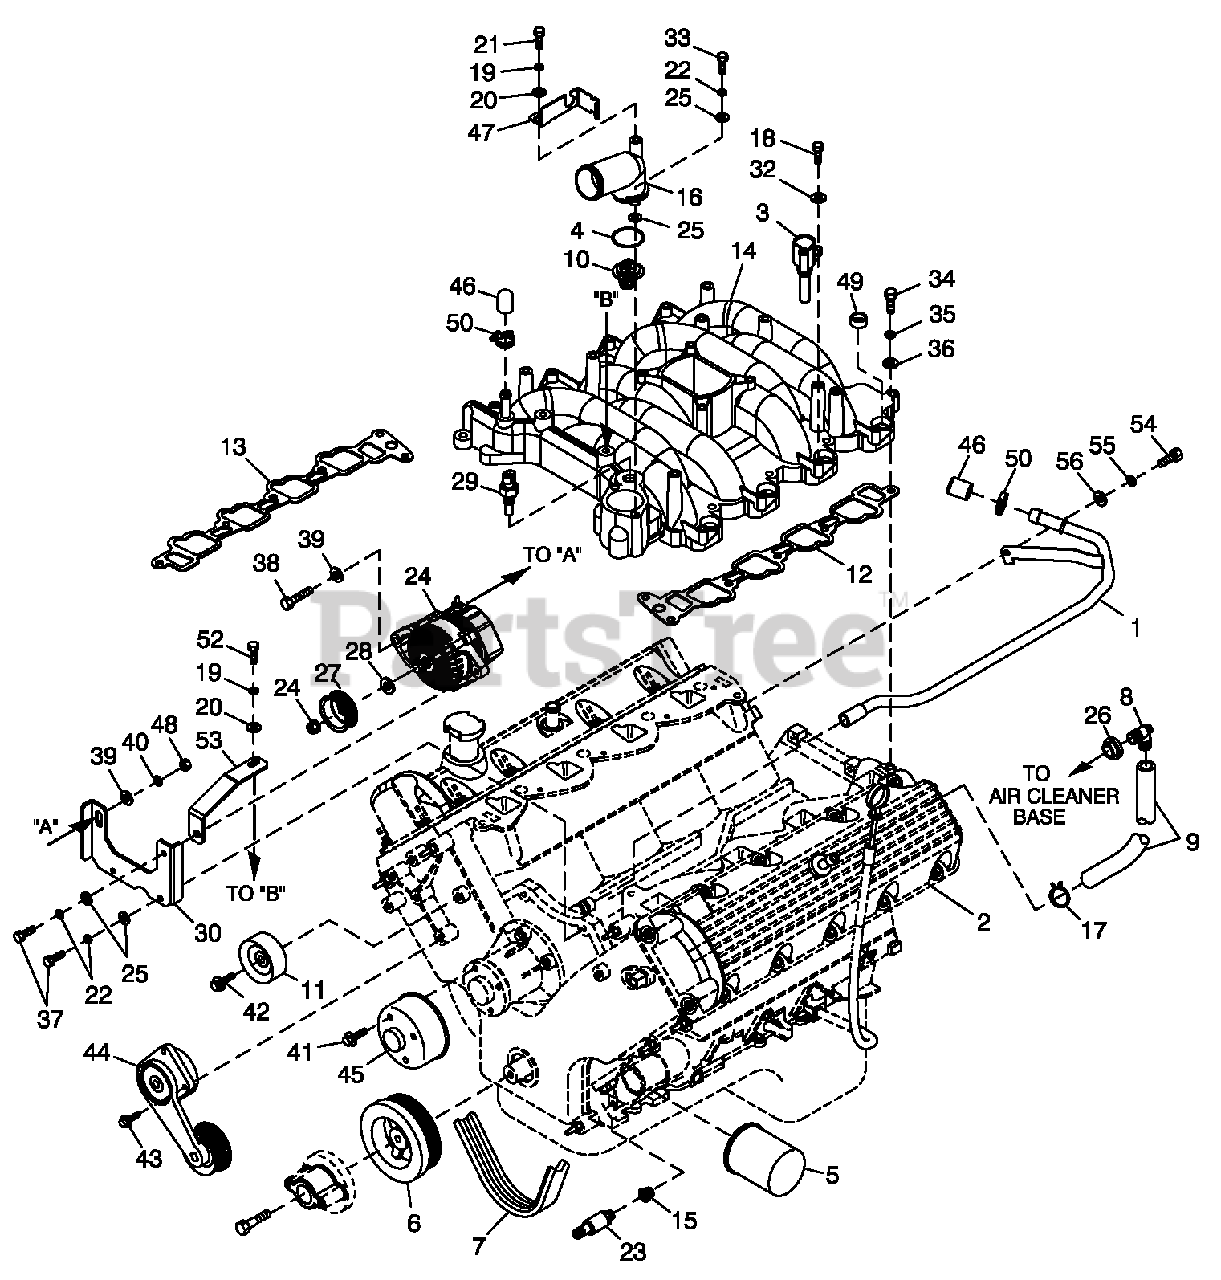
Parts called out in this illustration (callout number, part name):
1	TUBE COOLANT 4.6L
2	ENGINE 4.6L G3 (RWD)
3	IGNITION COIL ASSY
4	GASKET THERMOSTAT HOUSING G3
5	OIL FILTER
6	REWORK HARMONIC BALANCER
7	BELT SERPENTINE 54.72"
8	BARBED EL 90 3/4 PLASTIC
9	HOSE 3/4 ID SAE-30R2 (21"LG)
10	THERMOSTAT ASSY
11	PULLEY FAN BELT
12	GASKET INTAKE MANIFOLD LEFT
13	GASKET INTAKE MANIFOLD RIGHT
14	MANIFOLD INTAKE 4.6L G3 (RWD)
15	BUSHING REDUCER 3/8 TO 1/8 GAL
16	CONNECTION WATER OUTLET
17	CLAMP HOSE BAND .88"
18	SCREW HHC M5-0.8 X 25 G8.8
19	WASHER LOCK M6-1/4
20	WASHER FLAT 1/4 ZINC
21	SCREW HHC M6-1.0 X 20 G8.8
22	WASHER LOCK M8-5/16
23	SENDER OIL PRESSURE 1/8"NPT
24	ALTERNATOR DC W/OUT PULLEY
25	WASHER FLAT 5/16-M8 ZINC
26	GROMMET
27	PULLEY 160 OD DC ALTERNATOR
28	SPACER DC ALTERNATOR PULLEY
29	TEMPERATURE SENDER, DELPHI
30	BRACKET DC ALTERNATOR 4.6L
32	WASHER FLAT M5
33	SCREW HHC M8-1.25 X 90 G8.8
34	SCREW HHC M8-1.25 X 50 G8.8
35	WASHER LOCK M8-5/16
36	WASHER FLAT 5/16-M8 ZINC
37	SCREW HHC M8-1.25 X 25 G8.8
38	SCREW HHC M10-1.5 X 45 G8.8 FT
39	WASHER FLAT 3/8-M10 ZINC
40	WASHER LOCK M10
41	SCREW WP PULLEY M8-1.25 X 19
42	BOLT HEX FL HD M8-1.25 X 28
43	BOLT HEX FL HD M8-1.25 X 31
44	TENSIONER, ENG. AUTOMATIC BELT
45	PULLEY ENGINE WATER PUMP
46	CAP ANTIFREEZE RUBBER
47	BRACKET, SIGNAL CONDITIONER
48	NUT HEX M10-1.5 G8 YEL CHR
49	PLUG EXPANSION 14 O.D.
50	CLAMP HOSE #10 .56-1.06
52	SCREW HHC M6-1.0 X 16 G8.8
53	ALTERNATOR STRAP
54	SCREW HHC M8-1.25 X 20 G8.8
55	WASHER LOCK M8-5/16
56	WASHER FLAT 5/16-M8 ZINC
